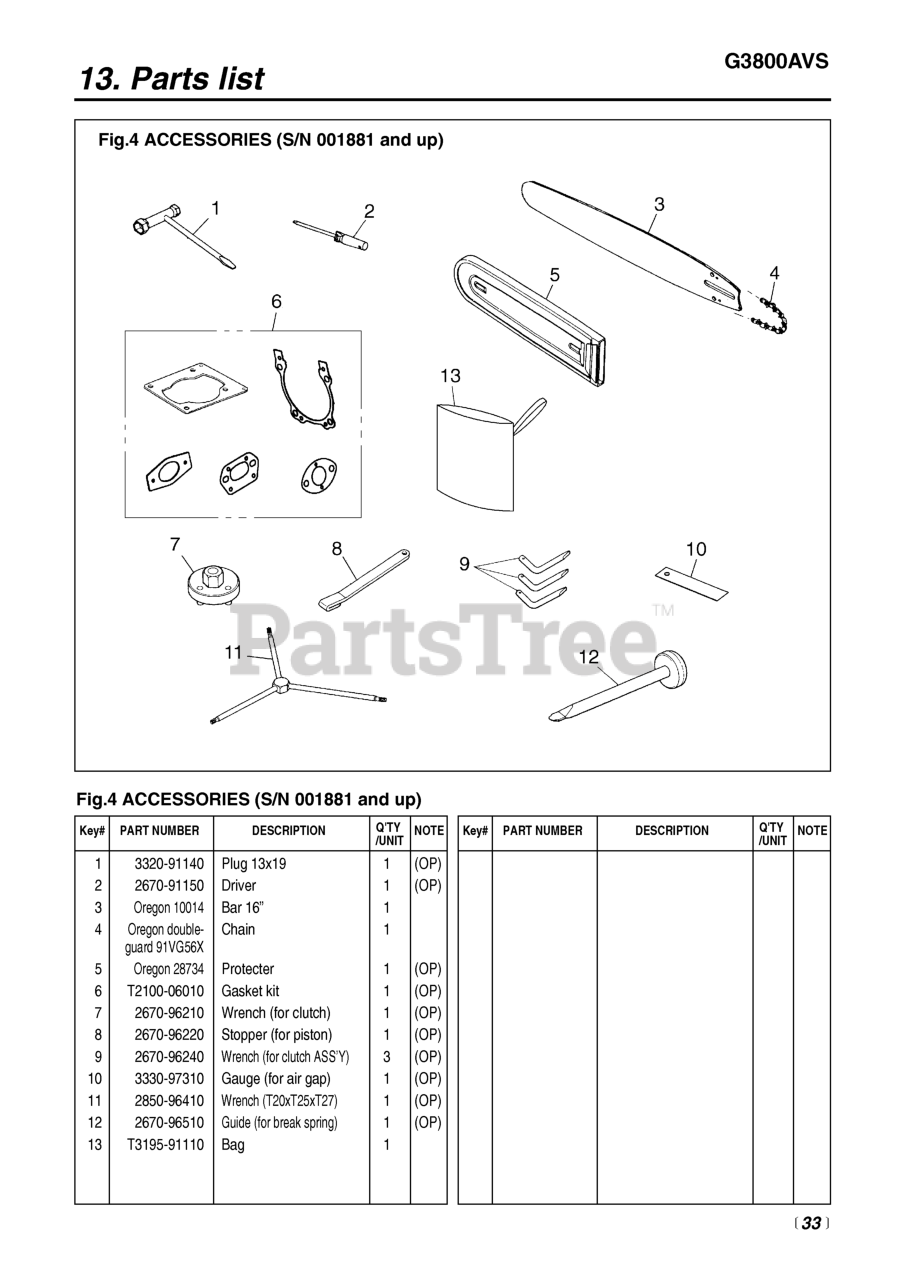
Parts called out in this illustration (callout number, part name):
1	WRENCH, PLUG
2	SCREWDRIVER
3	BAR 16
5	PROTECTOR (OREGON 28734)
6	KIT, GASKET (G3800AVS)
7	WRENCH (TOOL)
8	STOPPER (TOOL)
9	WRENCH (TOOL)
10	GAUGE (TOOL)
11	WRENCH (RPLS. 2670-96410)
12	GUIDE (TOOL)
